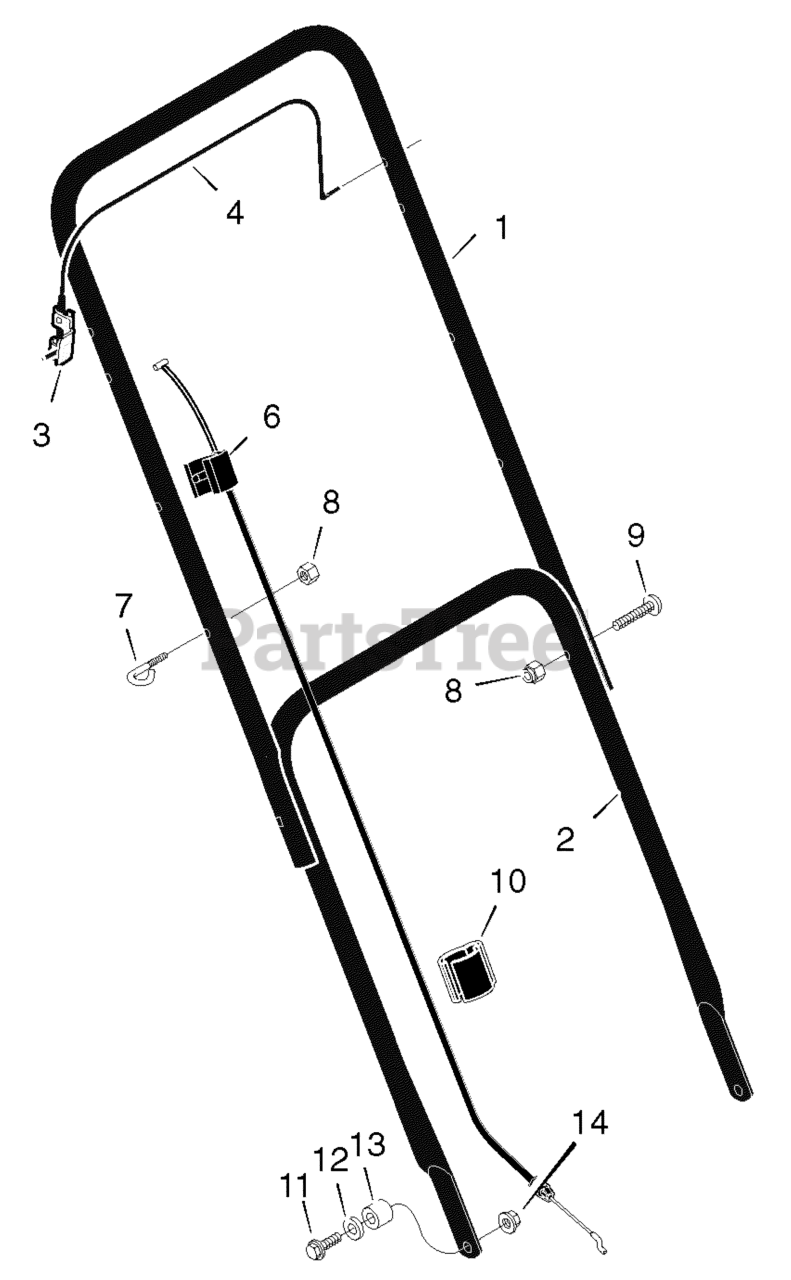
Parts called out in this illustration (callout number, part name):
1	Handle, Upper (Black)
2	Handle, Lower (Black)
3	Bracket, Stop Lever
4	Lever, Stop
6	Engine Stop Cable
7	Guide, Rope
8	Locknut
10	Clip, Cable
11	Bolt
12	Washer
13	Spacer
14	Nut
